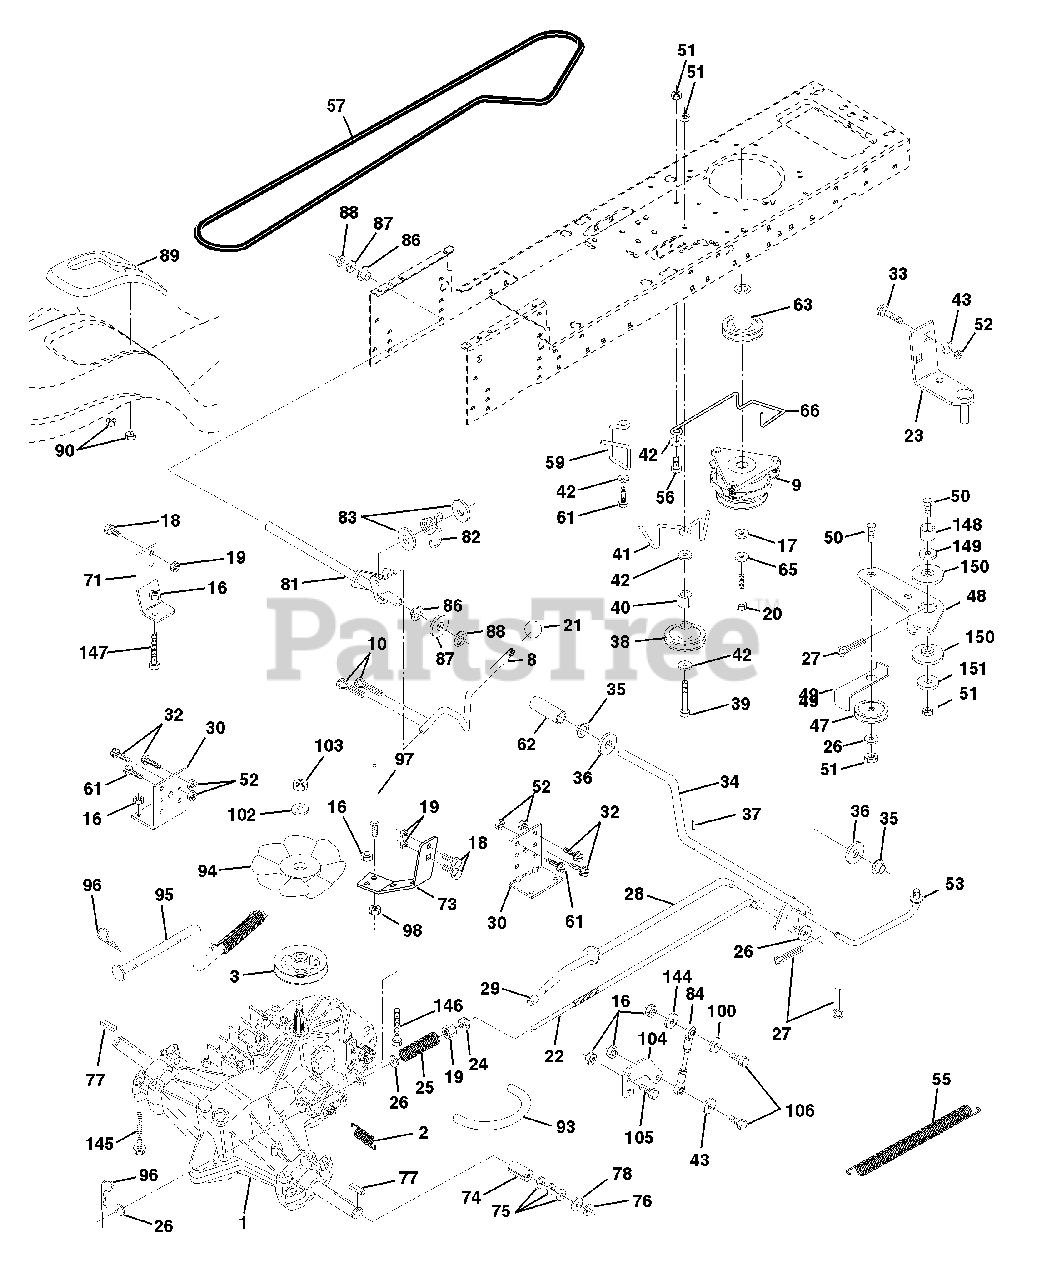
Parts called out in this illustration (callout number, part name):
1	Transaxle w/cas Hydro 310-0650
2	Spring, Return, Brake
3	Pulley, Transaxle Hydro 750 LT
8	Rod Shift STLT
9	Clutch Electric
10	Pin Cotter 1/8 x 1 CAD
15	Bolt Hex 5/16-18 Unc Flghd
16	Nut Lock Hex W/Ins. 5/16-18 Unc P
17	Washer 1-1/2 OD x 15/32 ID x .250
18	Bolt Fin Hex 3/8-16 Unc x 1 Gr.5
19	Nut Lock Hex W/Ins 3/8-16 Unc
20	Bolt, Hex 7/16-20 x 4-1/4 Ga. 5
21	Knob Deluxe 1/2-13 UNC BLK/BLK
22	Rod, Brake Hydro
23	Bracket Asm Mtg CL
24	Nut Hex Jam 3/8-16 UNC
25	Spring, Brake Rod
26	Washer
27	Pin Cotter 1/8 x 3/4 CAD.
28	Rod, Parking Brake
29	Cap, Parking Brake
30	Bracket, Transaxle
32	Bolt Hex Hd 5/16-18 Unc x 3/4
33	Bolt Carriage 5/16-18 UNC x 3/4
34	Shaft, Foot Pedal
35	Bearing, Nylon
37	Pin, Roll
38	Pulley, Idler, Flat
40	Spacer Split
41	Keeper, Belt Idler
42	Washer 13/32 x 13/16 x 12 Ga
43	Washer 11/32 x 5/8 x 12 Ga.
47	Pulley, Idler, V-Groove Plastic
48	Bellcrank Clutch Grnd Drv STL
49	Retainer, Belt Style Spring
50	Bolt
52	Nut Crown Lock 5/16-18
53	Link, Clutch
55	Spring, Return, Clutch
56	Bolt, Fin Hex 3/8-16 UNC x 1 1/4
57	V-Belt, Ground Drive
59	Keeper, Center Span
61	Screw Thdrol. 3/8-16 x 3/4 Ty. TT
62	Cover, Pedal Premium
63	Pulley, Engine
65	Washer Lock Hvy HLCL Spr 7/16
66	Keeper Belt Engine
71	Strap Torque Lh Hydro 18/20" T
73	Strap Torque Rh Hydro 0650
74	Spacer, Split
75	Washer 25/32 x 1-1/4 x 16 Ga.
77	Key, Square
78	Washer 25/32 x 1-5/8 x 16 Ga
81	Shaft Asm. Cross Hydro 20" Tires
82	Spring Torsion T/A
83	Washer 17/32 x 3/4 x 16 Ga.
84	Rod, Tie Hydro 20" Tires SPH Ball 4.75
86	Bushing Rod Strig. 629/632 ID
87	Washer 21/32 x 1-1/4 x 16 Ga.
88	Ring Klip #5304-62
89	Console, Shift Hydro STLT
90	Nut Self-Thd Wsh-Hd 1/4 Zinc
91	Bolt Fin Hex 5/16-18 x 2-1/4
92	Bolt Fin Hex 5/16-18 Unc x 1-1/2
93	Line Fuel Hydro 4"
94	Fan, Hydro 7"
95	Control Asm. Bypass Hydro
96	Retainer Spring 1" Zinc/Cad
97	Keeper Belt Rh Hydro 0750.18/20"
98	Nut Keps Hex 3/8-16 Unc
100	Washer 11/32 x 3/4 x 16 Ga.
102	Washer Belleville .501D x 1.50D
103	Nut Hex Jam Toplock 1/4-20 Unf
104	Arm, Control Hydro
105	Screw Cap Hex 5/16 x 18 x 1
106	Bolt Fin Hex 5/16-18 Unc x 1-1/4
144	Washer 11/32 x 5/8 x 16 Ga.
149	Spacer Retainer PM Mower
150	Bushing Nylon Collered
151	Washer 13/32 x 2 x 10 Ga.
